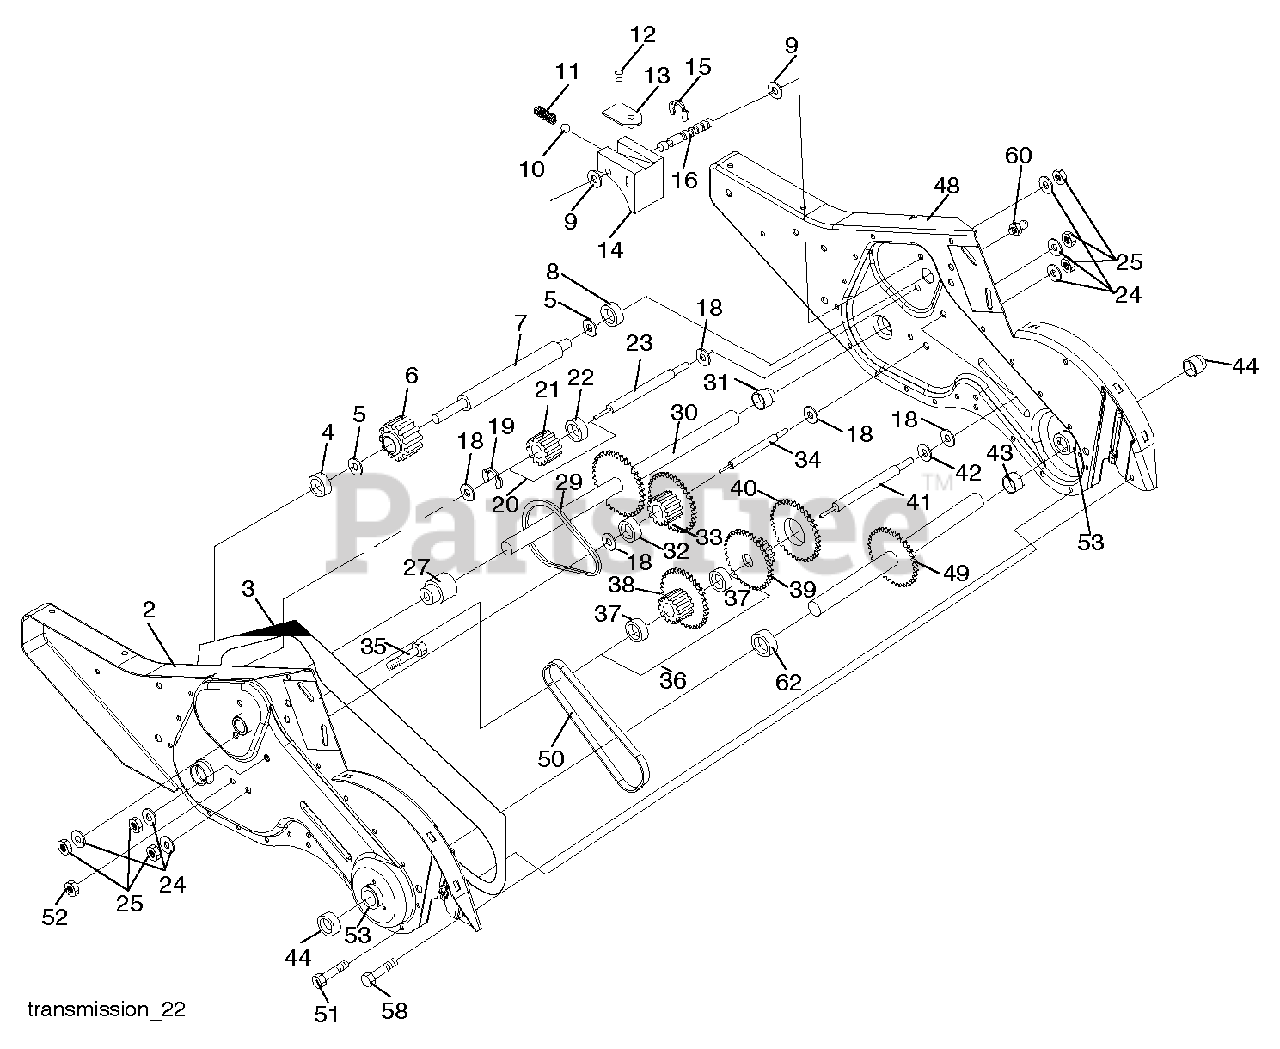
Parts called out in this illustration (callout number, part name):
2	GEARCASE.ASM.CRT.LH.W/BEARING
3	GASKET, GEARCASE
4	NEEDLE BRNG LT
5	THRUST WASHER
6	Pinion Input Gear, CRT Tiller
7	SHAFT.INPUT."D".TILLER
8	BEARING TI
9	WASHER, SEAL
10	STEEL BALL KIT
11	SPRING-SHIFT CRT
12	O-RING TI
13	SHIFTING ARM
14	SHIFT FORK TI
15	KLIP RING
16	SHAFT.SHIFTER.TILLER
19	KLIP RING
20	GEAR ASSY CRT
21	GEAR-REV IDLR CRT
22	NEEDLE BEARING TI
23	SHAFT CRT
24	LOCKWASHER
27	BEARING.GROUND.DRIVE
29	CHAIN CRT
30	GROUND SHAFT ASS'Y
31	BEARING, SHAFT RH CRT
32	SPACER TI
33	SPRCKT 8 GEAR CRT
34	SHAFT.SECONDARY.REDUCTION.CRT
35	SCRW WHIZ LOK CRT
36	SPROCKET ASS'Y W/BRG
37	BEARING
38	SPROCKET, TINE
39	GEAR TI
41	SHAFT.REDUCTION.TILLER
42	BRNG RACE T
43	SPACER TI
44	SEAL ASM, OIL
48	GEARCASE.ASM.CRT.RH.W/BEARING
49	SHAFT.ASM.TINE
50	CHAIN.TILLER
53	BEARING KIT
58	BOLT SHOULDER 1/4-20 UNC X.875
60	FITTING.GREASE.TAPERED
